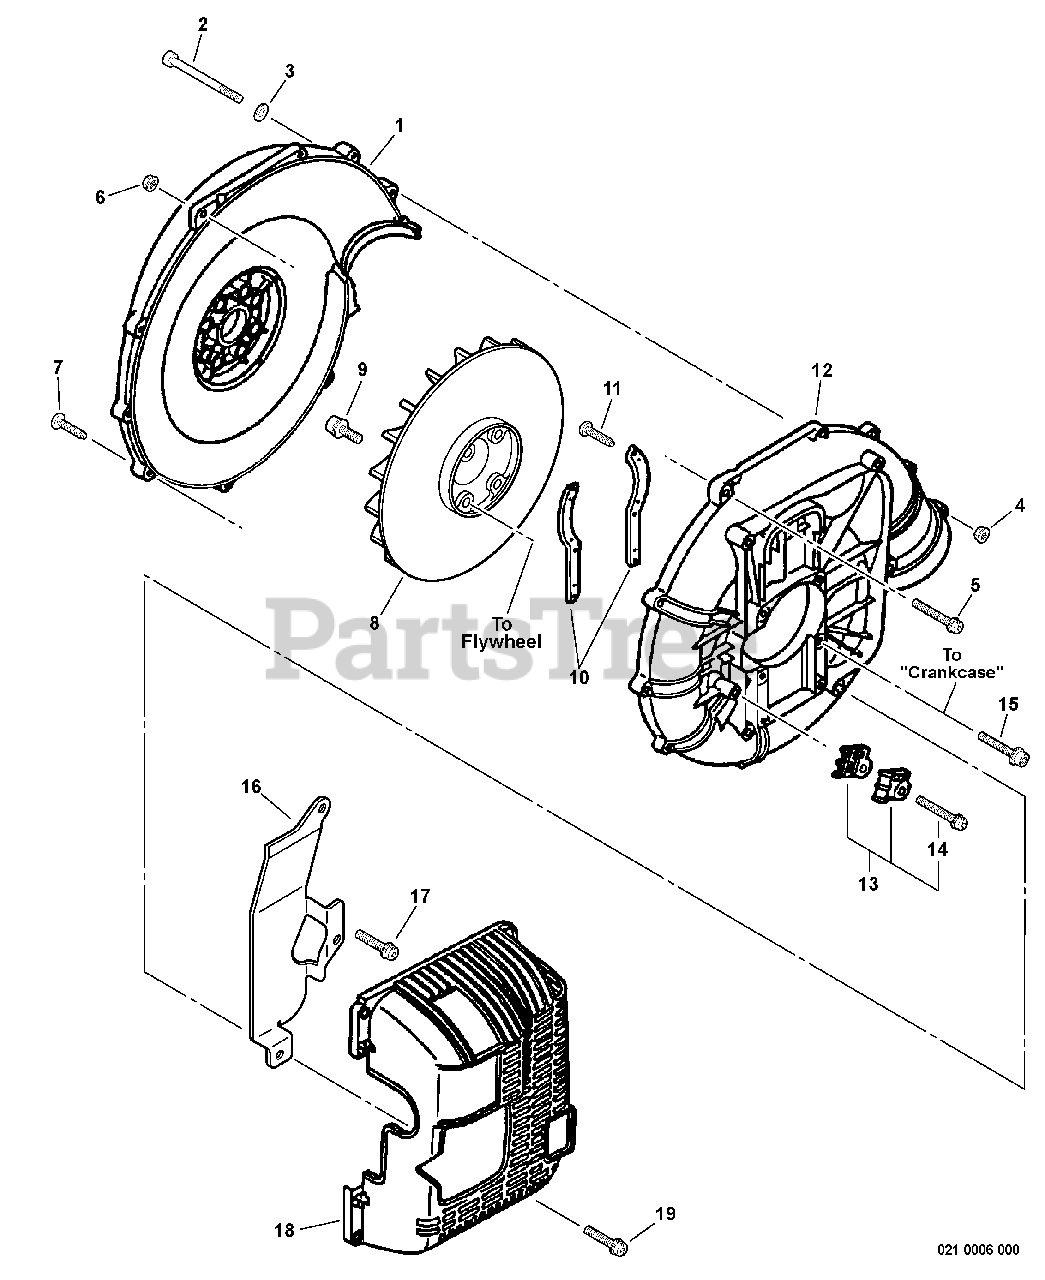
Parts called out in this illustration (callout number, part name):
1	COVER, FAN - INNER -- GRAY
2	SCREW - 5X60
3	WASHER - 5
4	NUT - 5 -- FLANGE
5	SCREW - 5X40
6	NUT - 5 -- FLANGE
7	SCREW - 5X30
8	FAN
9	SCREW - 5X20
10	BRACKET, ENGINE
11	SCREW - 3X12 -- TAPPING
12	COVER, FAN - OUTER -- GRAY
13	CABLE HOLDER KIT
14	SCREW - 5X25
15	SCREW - 5X32
16	INSULATOR
17	SCREW - 5X10
18	COVER, ENGINE
19	SCREW - 5X18
